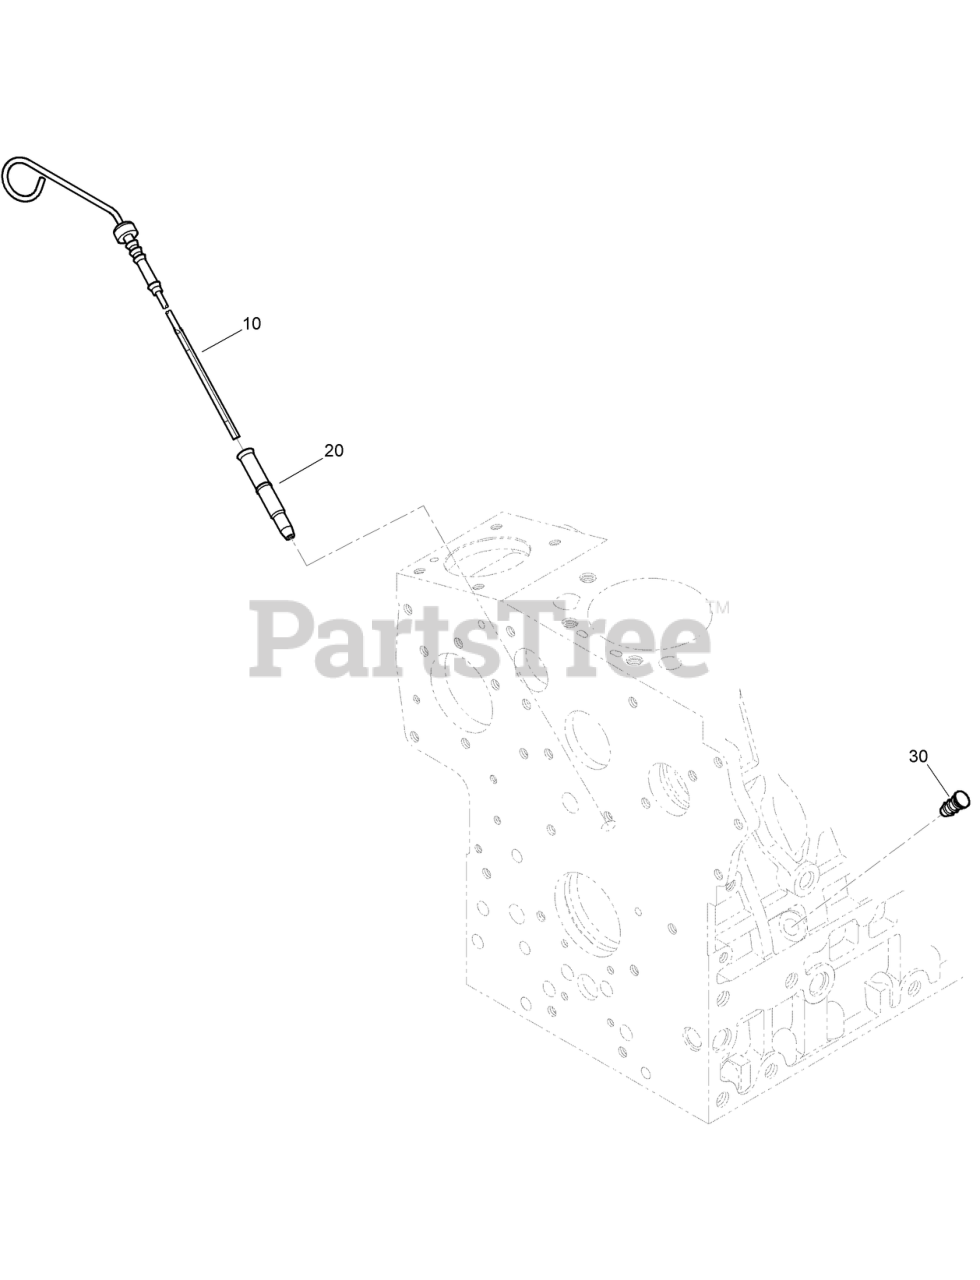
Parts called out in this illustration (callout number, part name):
10	GAUGE-OIL, ENGINE
20	GUIDE-GAUGE, OIL
30	PLUG-GAUGE, OIL
